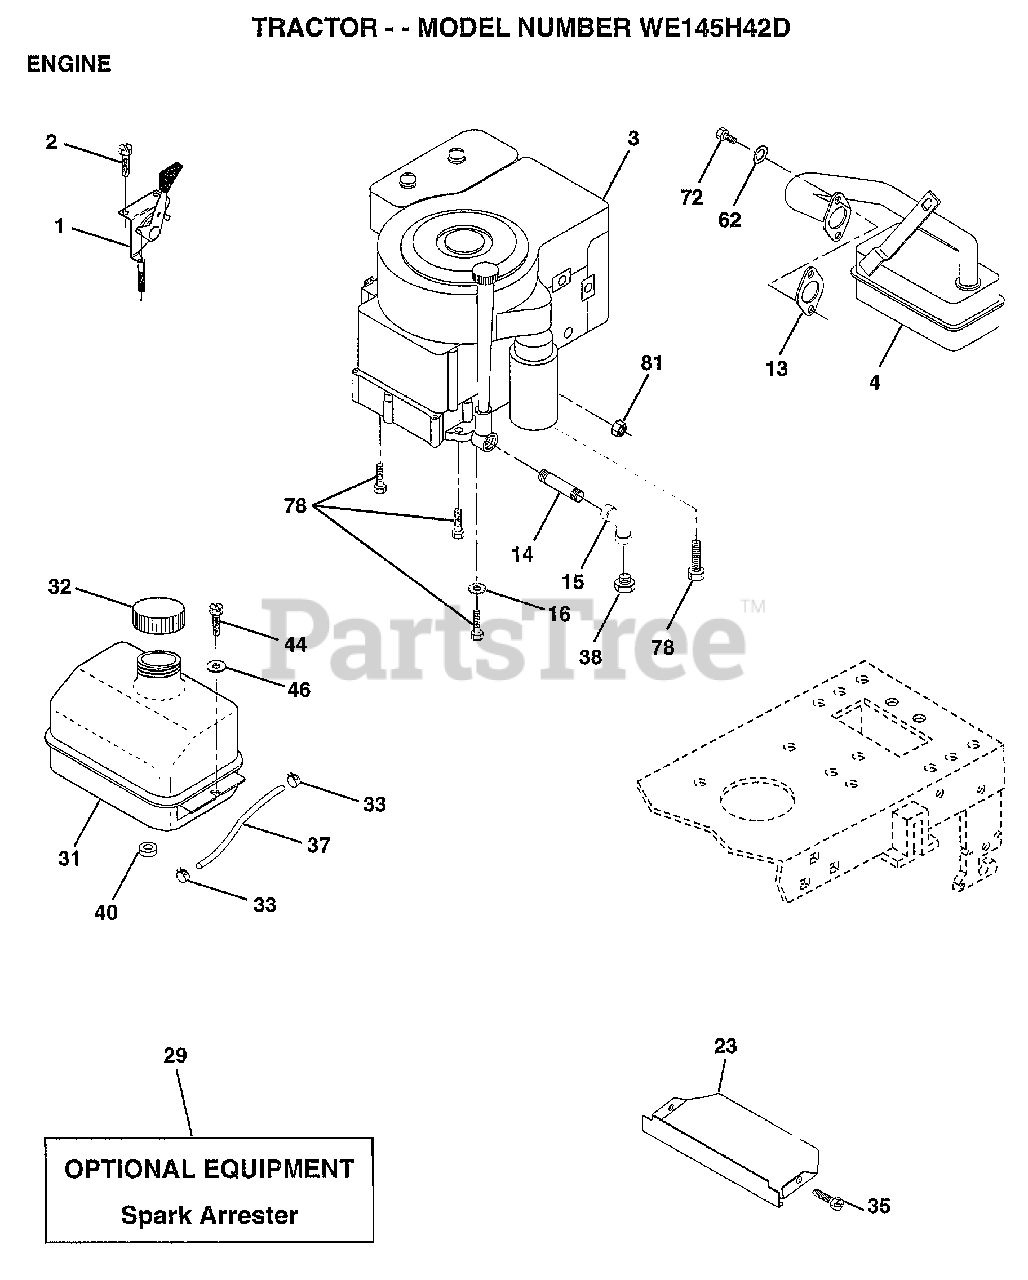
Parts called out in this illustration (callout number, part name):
1	CONTROL THROTTLE
2	SCREW LT
4	MUFFLER
13	GASKET ENG 1 313 LD TIN PLATED
14	PIPE NIPPLE
15	ELBOW
16	LOCKWASHER
23	SHIELD.BRN/DBR.GD
31	TANK.FUEL.LT.
32	CAP ASM FUEL
33	HOSE CLAMP
35	SCREW
37	LINE FUEL
44	SCREW HEX CRT
46	WASHER
62	LOCKWASHER
72	SCREW
78	SCREW
81	NUT
